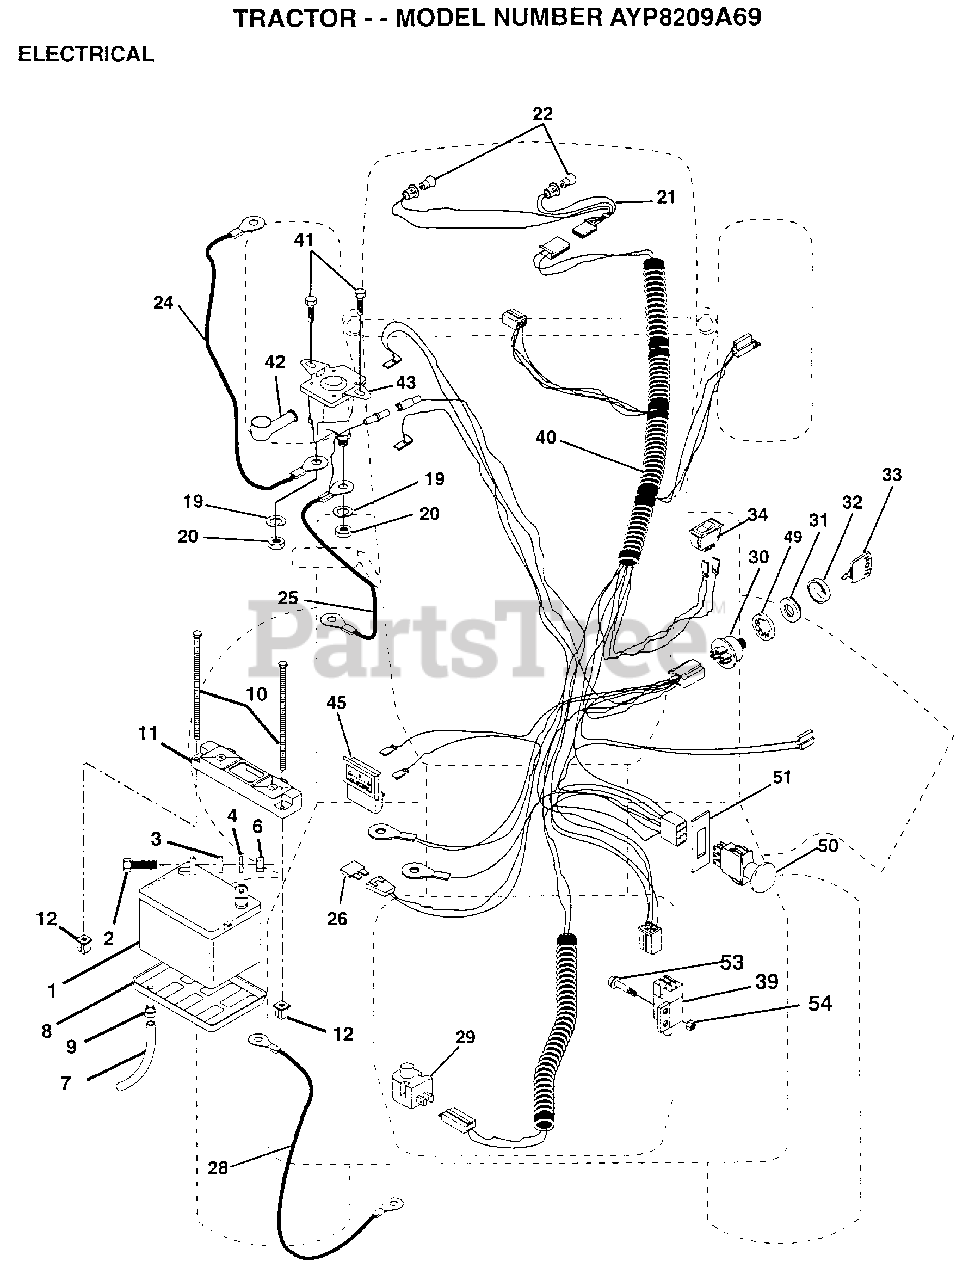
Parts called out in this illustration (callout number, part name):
2	BOLT LT
3	WASHER
4	LOCKWASHER
7	"DRAIN TU T, BATT"
8	"TRAY T, BATTERY"
9	HOSE CLAMP T
20	NUT
21	"HARNESS,LIGHT SOC"
22	HEADLAMP BULB
24	CABLE-BATTERY T
25	CABLE.6GA.12.5.
26	FUSE HYT
28	CABLE T
29	SWITCH SEAT
32	COVER KEY SWITCH
33	KEY MLD GEN DELTA
34	SWITCH LT
39	SWITCH INTERLOCKT
40	HARNESS.IGN.SRSGT
41	SCREW
45	AMMETER
49	LOCKWASHER
51	RING RETAIN PTO
53	SCREW
54	"NUT,KEPS"
70	HARNESS.ENG.VANII
